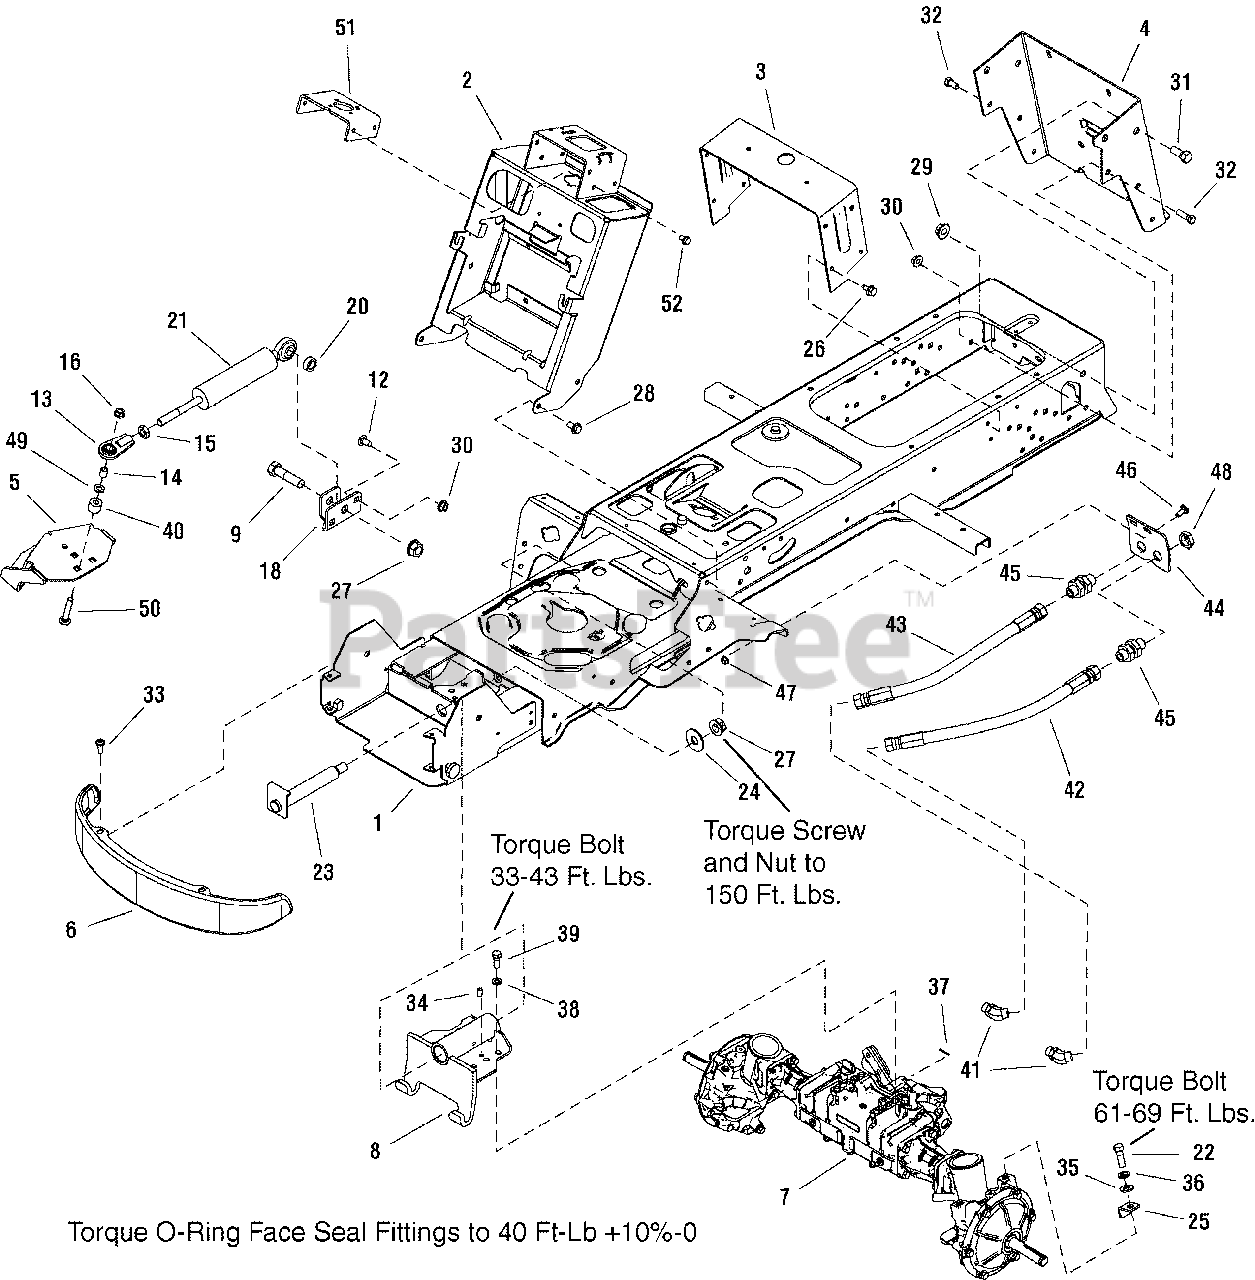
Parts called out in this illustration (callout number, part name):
2	TOWER & SUPPORT ASSEMBLY
3	SUPPORT, Seat Deck
4	BACKPLATE, Hitch
5	BRACKET ASSEMBLY, Steering 4WD
6	BUMPER, 4GA
7	AXLE ASSEMBLY, Front
8	PIVOT ASSEMBLY, Axle w/Bushings
9	CAPSCREW, Hex Head, 5/8-11 x 2-1/2 G5
12	BOLT, Carriage, 3/9-16 x 3/4, G5
13	JOINT, Ball 1/2-20
15	NUT, Hex Jam, 1/2-20
16	NUT, Hex Flange, 3/8-16 Two-Way Lock
18	BRACKET, Cylinder Mounting
21	CYLINDER, Hydraulic Steering
22	CAPSCREW, Hex Head, M12-1-3/4 x 35
23	SHAFT & BRACKET ASSEMBLY, Axle Pivot
24	WASHER, 5/8
25	STOP, "L" Steering
26	SCREW, Hex Washer Head Taptite, 5/16-18 x 3/4
27	NUT, Hex Flange 5/8-11 Two-Way Lock
28	SCREW, Hex Washer head, Taptite, 3/8-16 x 3/4
29	NUT, Hex Flange 1/2-13 Whiz Lock
30	NUT, Hex Flange 3/8-16 Whiz Lock
31	CAPSCREW, Hex Head 1/2-13 x 1 G5
32	CAPSCREW, Hex Head 3/8-16 x 1 G5
33	SCREW, Truss Head Torx Drive 5/16-18 x 7/8
35	WASHER, 1/2
36	LOCKWASHER, Spring
37	PIN, Cotter
38	LOCKWASHER, Spring
39	CAPSCREW, Hex Head
40	SPACER, Powdered Metal
41	FITTING, Hose Elbow, 45 Degree, 13/16-16 x 3/4-16
42	HOSE ASSEMBLY, Hydraulic
43	HOSE ASSEMBLY, Hydraulic
44	BRACKET, Hose Mounting 10GA
45	FITTING, Bulkhead Union 13/16-16
46	BOLT, Carriage, 5/16-18 x 3/4, G5
47	NUT, Hex KEPS, 5/16-18
48	NUT, Jam 13/16-16
49	WASHER, 3/8
50	BOLT, Carriage, 3/8-16 x 2-1/4, G5
51	SUPPORT, Steering Unit 7GA
52	CAPSCREW, Hex Washer Head Taptite 5/16-18 x 1/2
